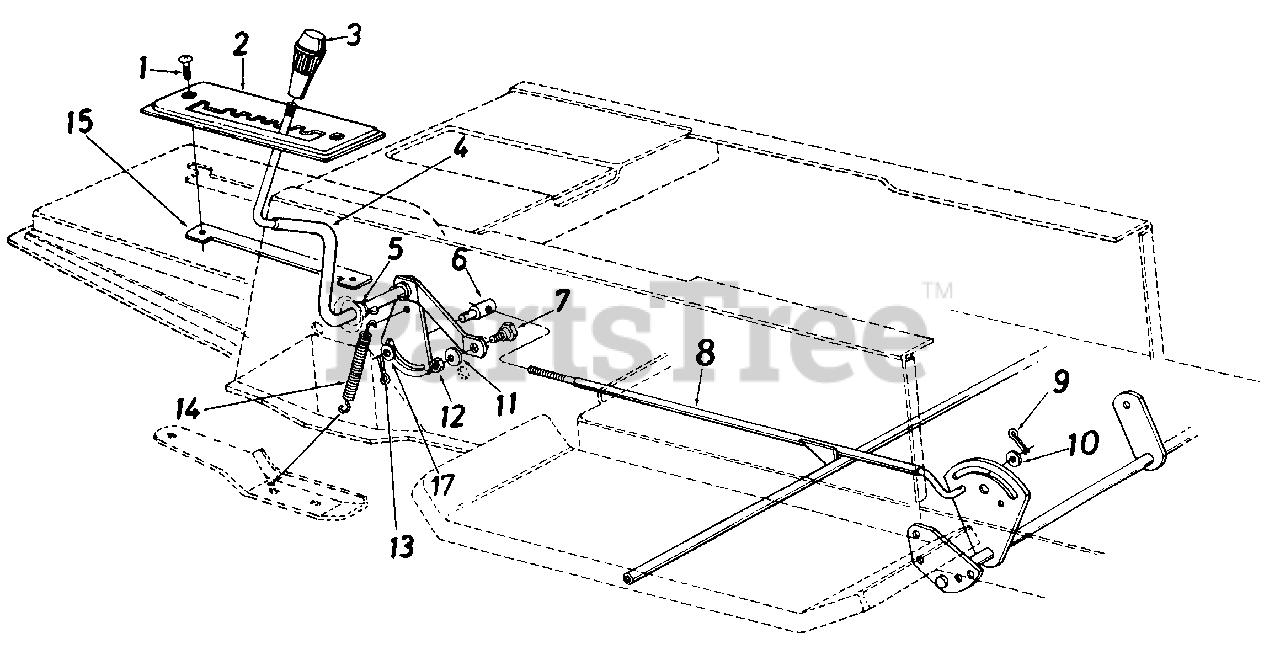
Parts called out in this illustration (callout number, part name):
1	Truss Mach. Scr. 20 x .75" Lg.
4	Speed Selector Cam Ass'y.
5	Flat Washer .53" l.D. x .93" O.D.
6	Ferrule 3/8-24 x .37 Dia.
7	Shoulder Bolt .435" Dia. x .160
8	Speed Control Rod Ass'y.
9	Cotter Pin 3/32" Dia. x .75" Lg.
10	Fl-Wash. .469" I.D. x .88" O.D.
11	L-Wash. 5/16" I.D.
12	Hex Nut 5/16-18 Thd.
13	Cotter Pin 3/32" Dia. x 75" Lg.
14	Spring 38n O.D. x 3.18" Lg.
15	Clamping Plate
17	Fl-Wash. .335" I.D. x .62" O.D.
